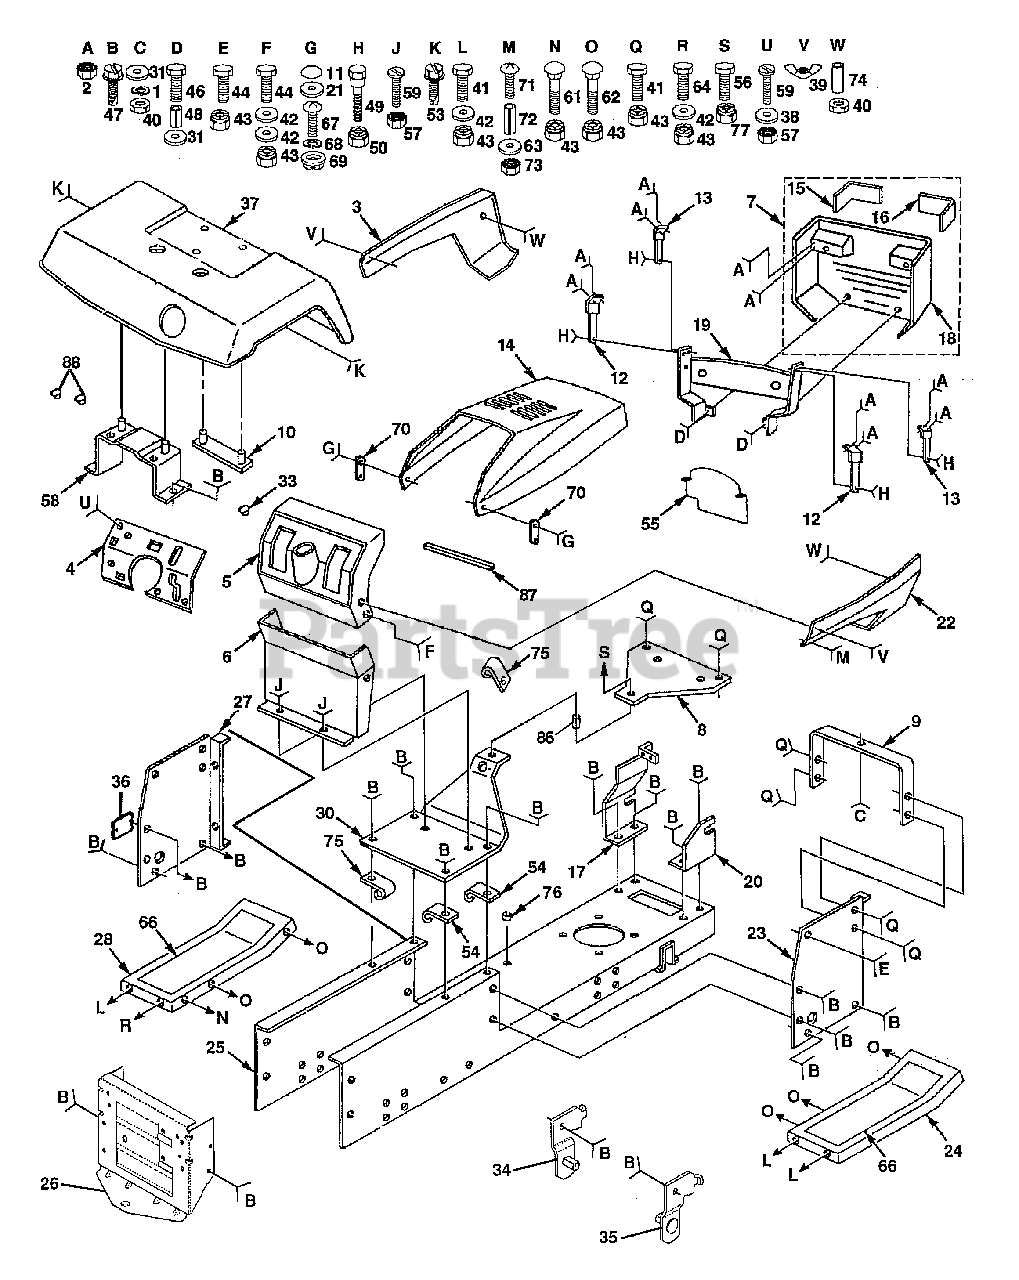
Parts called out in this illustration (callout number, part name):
1	Washer, Lock, Hvy Hlcl 1/4
2	Nut, Hex, Keps 1/4-20 UNC
3	Side Panel, LH
4	Plate, Dash
6	Dash, Lower
7	Grill Assembly
8	Plate, Battery Support
9	Support, Dash
10	Strap, Fender
11	Cap, Black
12	Strap Assembly, Hinge, Rear
13	Strap Assembly, Hinge, Front
14	Hood
15	Lens, Headlight, LH, Smoked
16	Lens, Headlight, RH, Smoked
17	Pivot Bracket Assembly, LH
18	Grille
19	Support Assembly, Grille
20	Pivot Bracket Assembly, RH
21	Washer, Cap
22	Side Panel, RH
23	Dash Panel, RH
24	Footrest, RH
25	Chassis
26	Drawbar
27	Dash Panel, LH
28	Footrest, LH
31	Washer 9/32 x 3/4 x 16 Gauge
33	Plug, Button
34	Pivot Bracket Assembly, Rear, LH
35	Pivot Bracket Assembly, Rear, RH
36	Cover Access
37	Fender
38	Washer 11/32 x 11/16 x 16 Gauge
39	Wing Nut, Plastic 1/4-20
40	Nut, Hex, Fin. 1/4-20 UNC
41	Bolt, Hex, Fin. 3/8-16 UNC x 3/4
42	Washer 13/32 x 13/16 x 12 Gauge
43	Nut, Crownlock 3/8-16 UNC
44	Bolt, Hex, Fin. 3/8-16 x 1
46	Bolt, Hex 1/4-20 x 2-1/2
47	Screw, Thd., Roll. 3/8-16 x 3/4
48	Spacer, Split
49	Bolt, Shoulder 1/4-20 UNC
50	Nut, Crownlock 1/4-20 UNC
53	Screw, Thd., Roll. 3/8-16 x 1/2
54	Clip, Insulator
55	Baffle, Vertical
56	Bolt, Hex, Fin. 5/16-18 UNC x 2
57	Nut, Hex, Keps 5/16-18 UNC
58	Bracket Fender
59	Screw, Machine 5/16-18 UNC x 3/4
61	Bolt, Carriage 3/8-16 UNC x 1
62	Bolt, Carriage 3/8-16 x 3/4
63	Washer 7/32 x 1/2 x 18 Gauge
64	Bolt, Hex, Fin. 3/8-16 UNC x 7/8
66	Pad, Footrest
67	Screw, Machine, Cross Pan Head #10-24 x 1/2
68	Washer, Lock #10
69	Nut, Weld
70	Latch, Chute
71	Screw, Machine, Cross Pan Head #10-24 x 1-1/4
72	Spacer, Split #10 x 3/4
73	Nut, Hex, Keps #10-24 UNC
74	Spacer 17/64 x 1/2 x 3/8
75	Clip, Fuel Line
76	Bushing, Snap Split
77	Nut,Lock, Hex w/Ins. 5/16-18
86	Spacer, Split
87	Strip, Foam 18"
88	Nut, Push, Nylon
